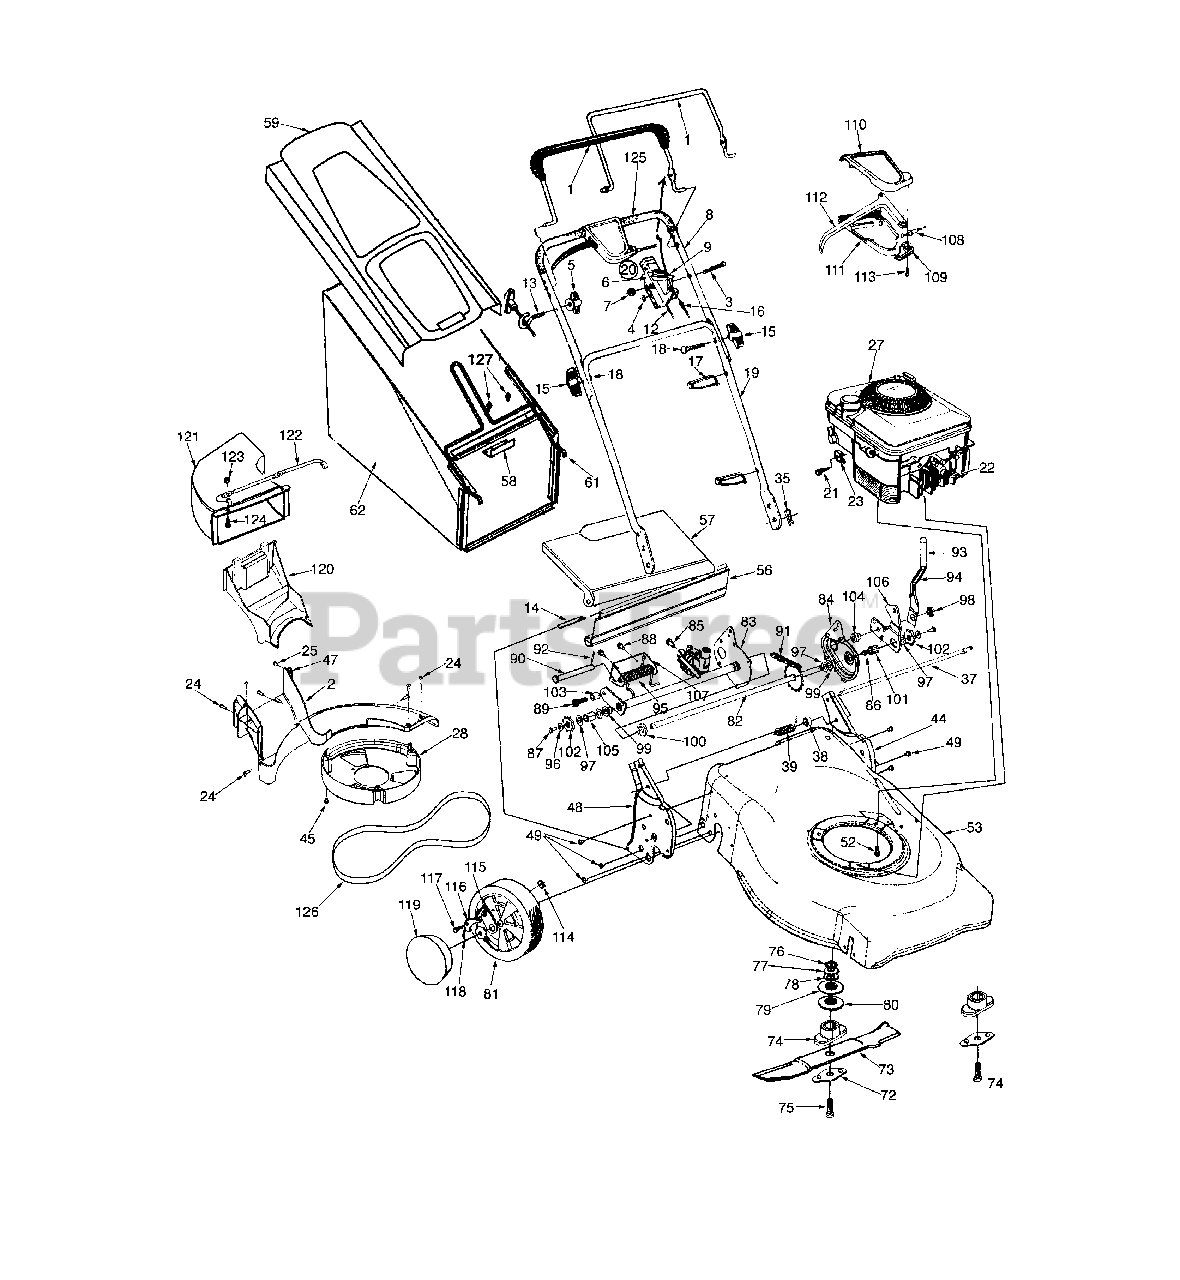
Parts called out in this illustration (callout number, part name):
2	Baffle
3	Oval C-Sunk Mach.-Scr.
4	Spr. Wash..66" I.D.
5	Handle Knob 1/4-20 Thd.
6	Throttle Body
7	Hex L-Nut 1/4-20
9	Throttle Lever
12	Throttle Control Wire-55"
13	Rope Guide
14	Wire-47" Lg.
15	Hand Knob
16	Control Cable-40.5"
17	Cable Tie
18	Cr.Hd. Bolt 5 / 16-18 x 2" Lg.
20	Throttle Box Comp.
21	Hex Self-Tap Scr. #10-32 x .62"
22	Spark Plug Boot
23	Cable Clamp (B&S)
24	Screw H.L. 12-24
25	Screw Mach. B Tapp.
27	Engine
28	Belt Cover
35	Int. Cotter Pin 5/15" Dia.
37	Pivot Rod
38	Spacer .385 I.D.
39	Torsion Spring L.H.
47	U-Nut
52	Hex L-Wash. Hd. Scr. 3/8-16 x 1"
62	Grass Bag - Black
72	Blade Bell Support
73	21" Mulching Blade w/Star
74	Blade Adaptor Kit w/Star
75	Hex Bolt 3/8-24 x 2.5 Lg.
76	Spacer
77	Fl. Wash. .885 x 1.85 x .06
78	Spr. Wash. .890 x .7x .04
79	Pulley Half- Upper
80	Pulley Half - Lower
81	Wheel Assembly
82	Axle Assy: RR
86	Scr. TT 1/4-20
87	Hx Cap Screw 1/4-20
88	Scr. AB 1/4-20
89	Scr 3/8 - 16 x 1.25
90	Pin - Clv. .500 Dia.x .4.62 Lg.
91	Chain:Endless 48:.500P x 22 Lg.
92	Pin-Cotter .125 O.D. x .75
93	Grip-Foam
94	Spring Lever
95	Torsion Spring
96	Bell Washer .265 x 75 x .062
97	Wash.-Flat .508 I.D. x 1.00.D.x .020
98	Nut - Shoulder .625 x .165 Lg.
99	Bearing-Fig Hex
100	Bearing-Fig. Hex
101	Bearing-Sleeve
102	Rachet Wheel
103	Spacer - .385 x .625 x .700
104	Spacer-Shld. .385 I.D.x .715 Lg.
105	Spacer Slv. .520 I.D. x .950 Lg.
106	Pivot Arm
109	Mounting Cap
110	Control Cover - Upper
111	Control Cover - Lower
112	Lever
113	Scr. AB #10-12:.75 Lg.
114	Weld Top L. 1/4-20
115	Pawl Plate
117	Shldr. Scr. .340 x .285
118	Spring, Ratchet
119	Gray (3-1/2" Dia) Hub Caps
120	Mulch Plug
121	Chute Deflector
122	Chute Mounting Rod
123	Hex-L-Nut 1/4-20 thd.
124	Mach. Scr. 1/4-20
125	Foam Grip
126	Belt
127	Scr. 1/4-14:.625 Hxindwsh
